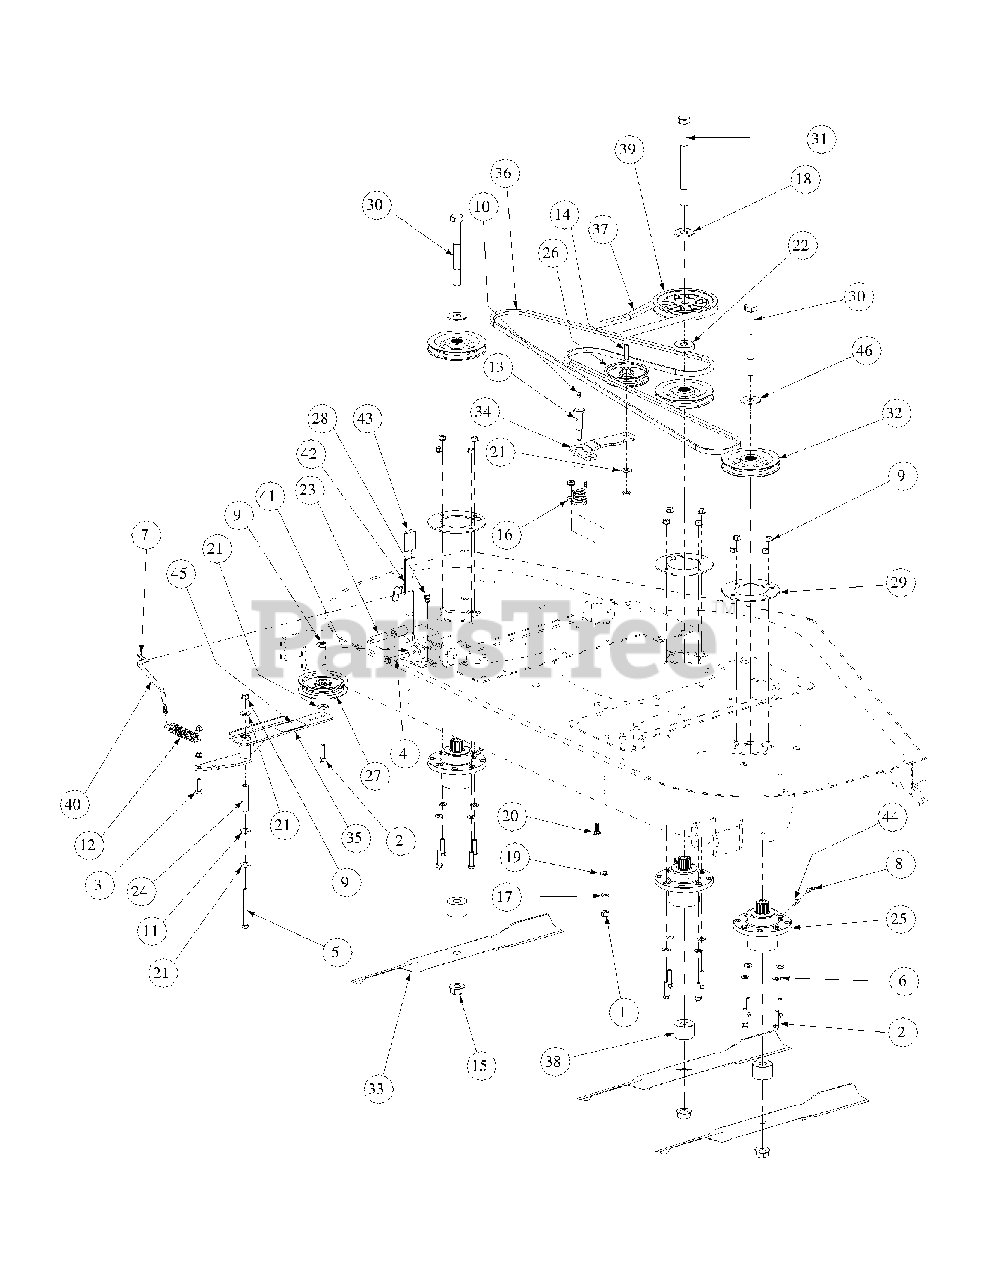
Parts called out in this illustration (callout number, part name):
1	Hex Nut, 7/16-14
2	Hex Cap Screw, 3/8-16 x 1-1/2
3	Hex Cap Screw, 3/8-16 x 1-1/4
4	Hex Cap Screw, 3/8-16 x 2-1/2
5	Hex Cap Screw, 3/8-16, 4.00
6	Flat Washer, 3/8
7	Cotter Pin, .072 x 1.12 Long
8	Taper Grease Fitting, 1/4-28, 45 degree
9	Flange Lock Hex Nut, 3/8-16
10	Grease Fitting, 1/4-28 x 3/16
11	Idler Washer
12	Extension Spring, 1.0 x OD x 5.00
13	Shoulder Screw, 7/16-14
14	Hex Carriage Screw, 3/8-16, 1.75
15	Flange Hex Nut, 3/4-16
16	Torsion Idler Spring
17	Lock Washer, 7/16
18	Flat Washer, .781 ID 2.00 OD, .105
19	Flat Washer, .469 ID, .875 OD, .105
20	Carriage Bolt, 3/8-16 x 1
21	Flat Washer, .406 ID, 1.0 OD, .105
22	Spacer, .76 ID x 2.0 OD x .477
23	Spacer, .39 ID x .63 OD x 1.75
24	Spacer, .39 ID x .625 OD x 2.75
25	Aluminum Spindle Assembly
26	Flat Pulley
27	Idler Pulley, 4.06 OD
28	Screw, TT, 3/8-16 x .50,
29	Aluminum Spindle Support Plate
30	Hex Cap Screw, 3/4-16, 7.50
31	Hex Cap Screw, 3/4-16, 9.00
32	V-Pulley, 5.75 OD
33	Bahia Blade, 25.0, .756 ID
34	Idler Arm Assembly, Deck
34	Bearing Sleeve
35	Idler Arm Assembly, Drive
35	Bearing Sleeve
36	V-Belt, B Section x 124.0 LG
37	V-Belt, B Section x 155 LG
38	Spacer, .760 ID x 2.00 OD x .330
39	V-Pulley, 6.95 OD x .750 Bore, Cast
40	Spring Tension Rod
41	Tension Idler U-Bracket
42	Handle Tension Weldment
43	Tension Idler Handle Grip
44	Straight Adapter Fitiing
45	Decal, Idler Location
46	Spacer .812 ID x .268 LG
